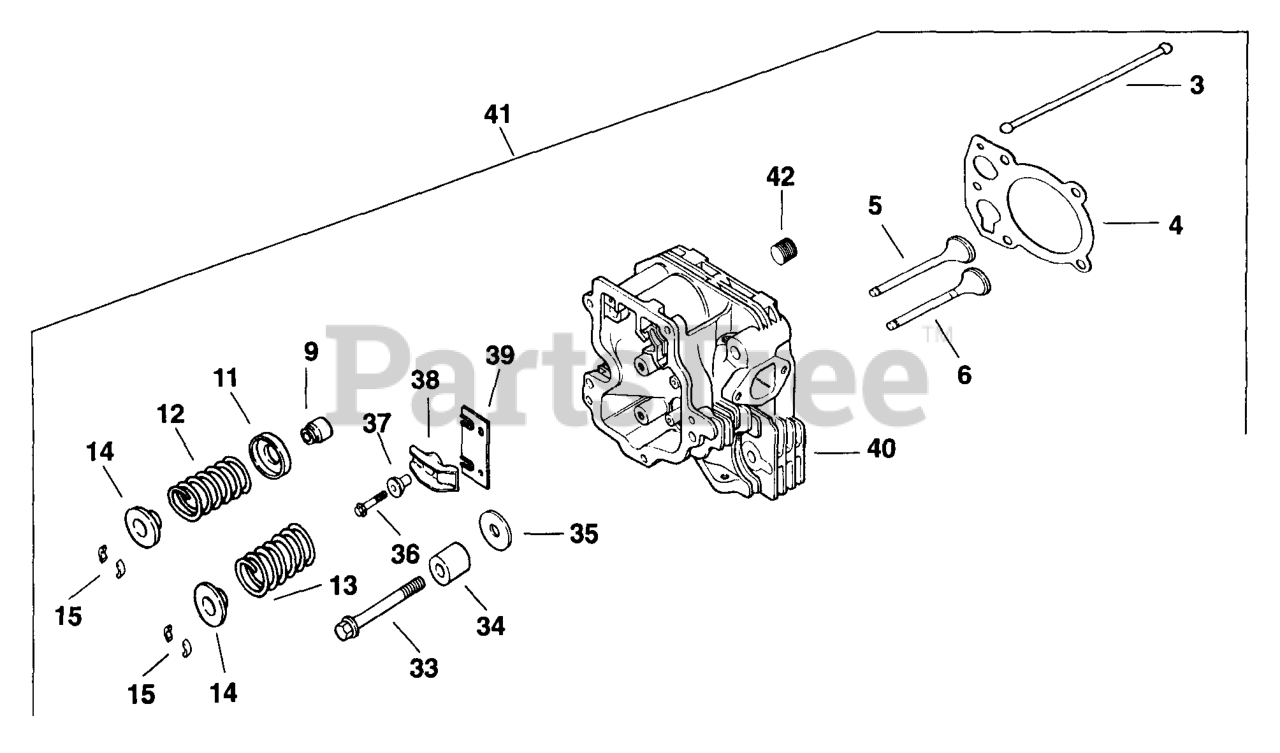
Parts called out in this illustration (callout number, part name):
4	GASKET, CYLINDER HEAD
5	VALVE, INTAKE
5	VALVE, INTAKE (.25 MM)
6	VALVE, EXHAUST
6	VALVE, EXHAUST (.25 MM)
9	SEAL - USE 24 032 05
11	RETAINER, SPRING
13	SPRING-(#DSC)
14	RETAINER, VALVE SPRING - USE 25 173 28-S
15	KIT, RETAINER
41	HEAD - USE 12 755 62
42	PLUG, CTSK PIPE 1/8" USE 25 139 60-S
